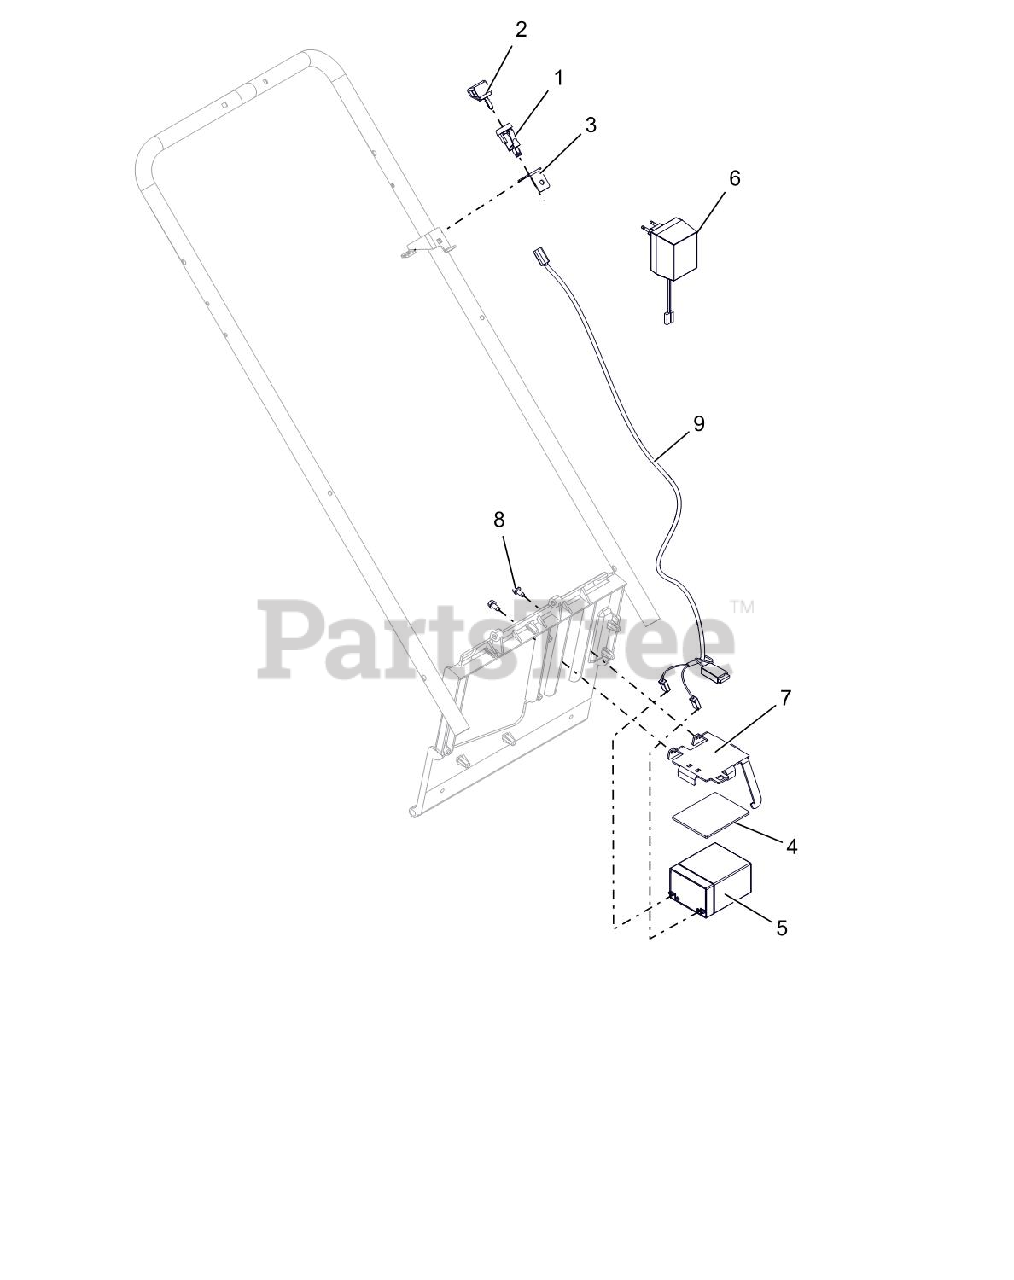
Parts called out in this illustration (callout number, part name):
1	SWITCH, KEY
2	KEYS, IGNITION
3	BRKT, KEY SWITCH
4	PAD, BATTERY, LM
5	BATTERY, AGM, 2.9AH, GNRL PRPS
6	CHARGER, BATTERY - CE
7	BRKT, BATTERY HOLD DOWN
8	SCR-TAP .25-20X.50 HWH TR YWZ
9	HARNESS, ELEC START
